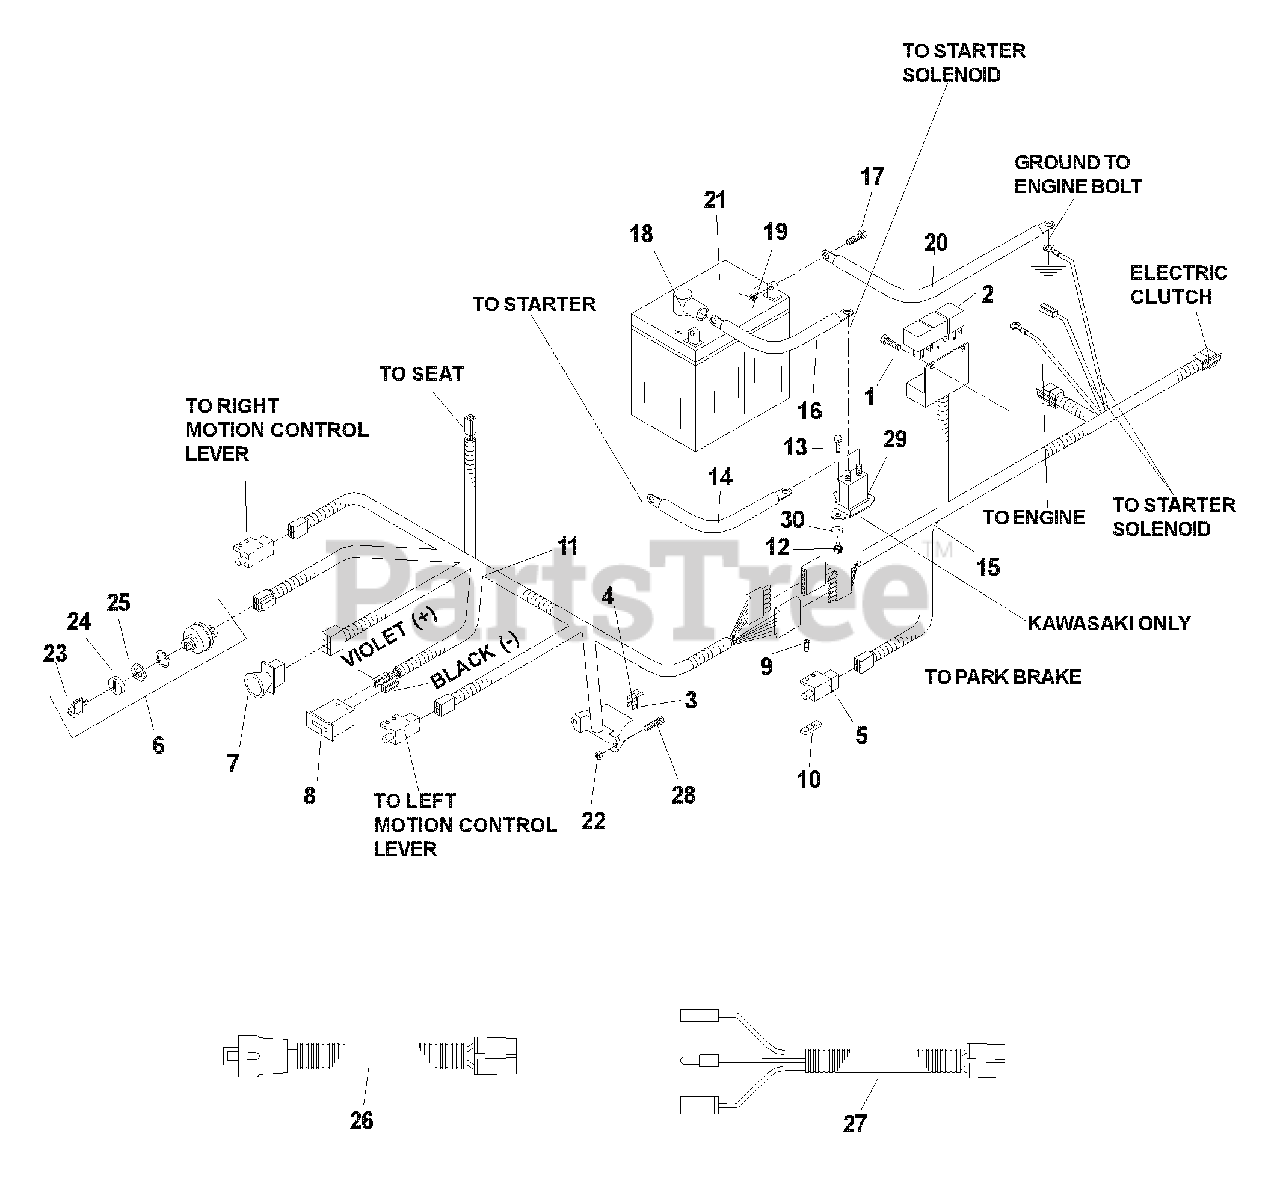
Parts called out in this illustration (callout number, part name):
1	#10 X 1/2 SELF TAPPING
3	7.5 AMP 32 VOLT ATO FUSE
4	20 AMP 32 VOLT ATO FUSE
5	INTERLOCK SWITCH
6	IGNITION SWITCH
7	BLADE SWITCH
8	HOUR METER
9	#10-24 X 5/8
10	TAPPED PLATE
11	HARNESS, CONSOLE
12	NUT 1/4C CENTERLOCK
13	HCS 1/4C X 5/8 (KAWASAKI ONLY)
14	CABLE POSITIVE (KAWASAKI ONLY)
15	HARNESS, FRAME
16	CABLE POSITIVE, LONG
17	HCS 5/16C X 3/4
19	NUT 5/16C CENTERLOCK
20	CABLE NEG.
21	BATTERY
22	NUT #10, NYLOC
23	KEY, PADDED
26	PIGTAIL FOR ENG. WIRING (KOHLER ONLY)
27	PIGTAIL FOR ENG. WIRING (KAWASAKI ONLY)
28	SCREW, #10C X 7/8
29	SOLENOID (KAWASAKI ONLY)
30	LOCKWASHER, 1/4, INTERNAL TOOTH
